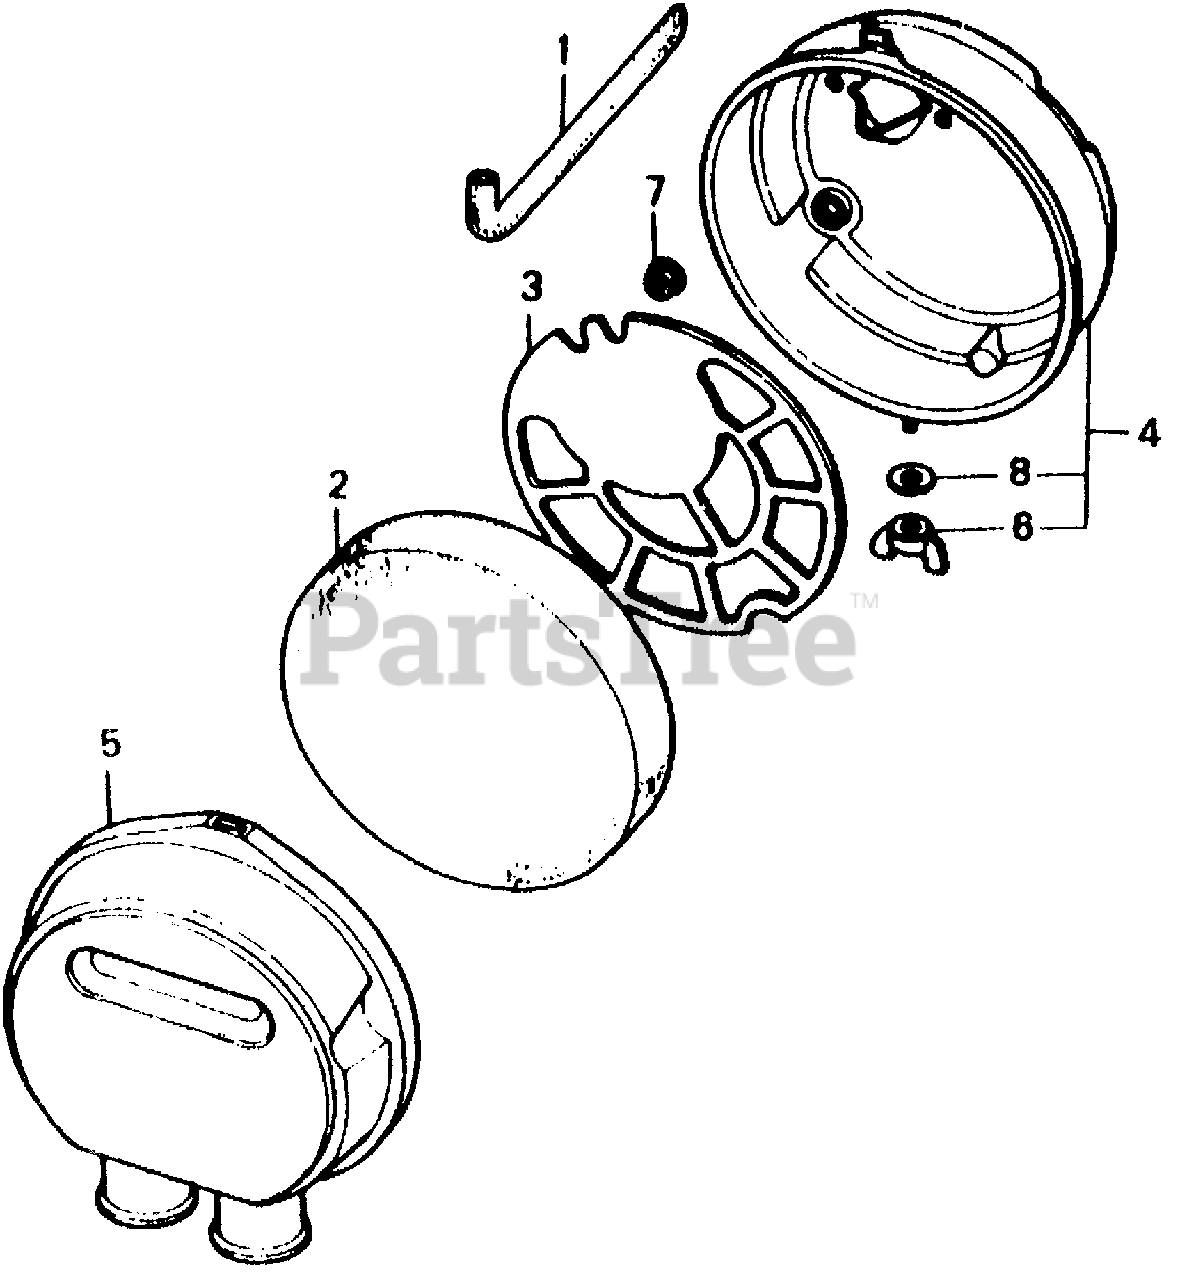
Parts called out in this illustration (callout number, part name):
1	TUBE, BREATHER
2	ELEMENT, AIR CLEANER
3	GRID, AIR CLEANER
4	HOUSING, AIR CLEANER
5	COVER, AIR CLEANER
6	WINGNUT, TOOL BOX SETTING
7	NUT, FLANGE (6MM)
8	WASHER, PLAIN (6MM)
